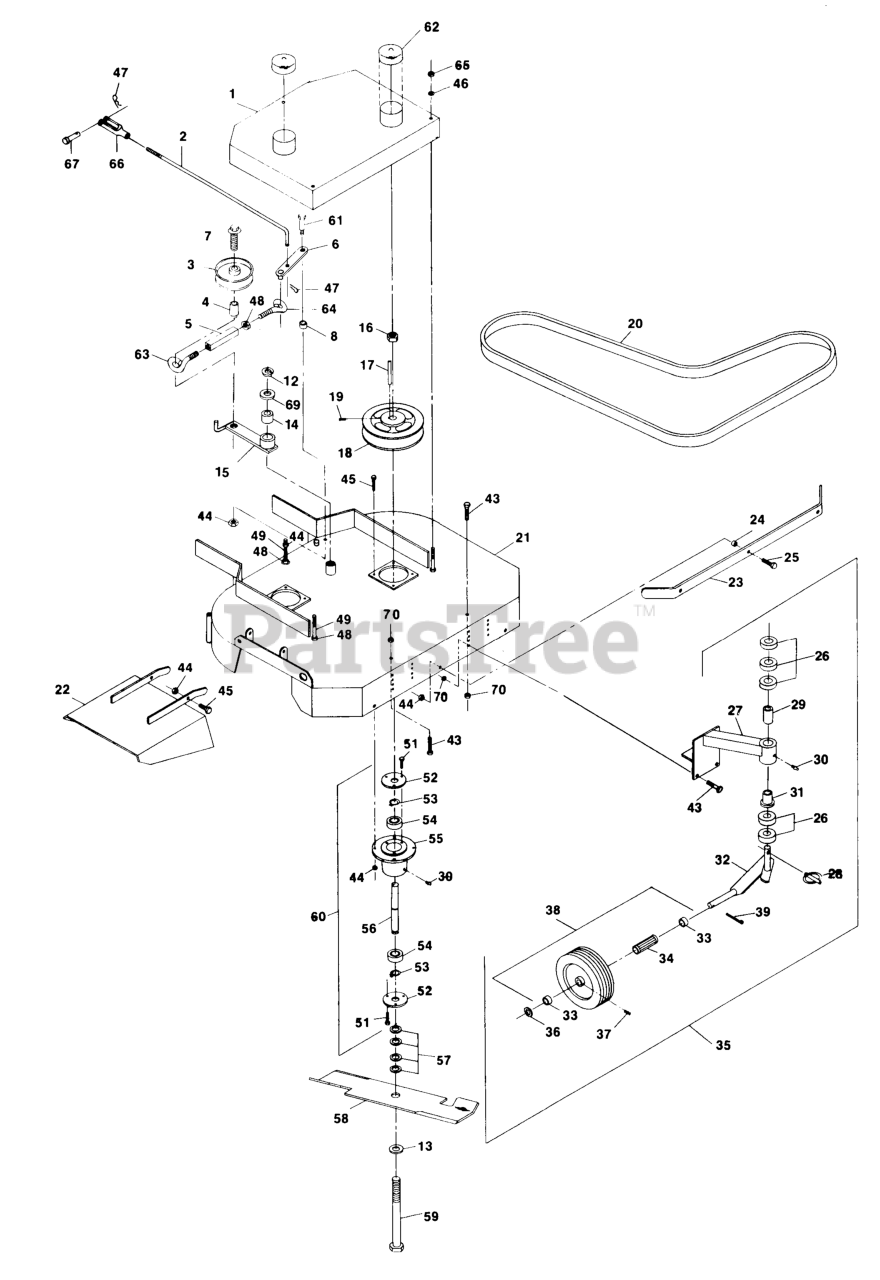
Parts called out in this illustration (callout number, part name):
5	BODY-TURNBUCKLE
14	BEARING,POWDERED METAL
18	PULLEY,CAST IRON
19	SCREW-SET
20	BELT,BLADE DRIVE
26	SPACER-CASTER
29	BEARING,STRAIGHT
32	WLD,STRUT CASTER
47	PIN-COTTER
49	BOLT,TAP HH
51	SCRWMACH PHS
55	HOUSING,CUTTER
56	SPINDLE,CUTTER
60	HOUSING,CUTTER COMPLETE
61	BOLT,SHLDR KSKH
62	CAP,SPINDLE GUARD
63	EYEBOLT-THREAD, LH
64	EYEBOLT-THREAD, RH
66	YOKE-ADJUSTABLE
67	PIN-CLEVIS
69	WASHER-SPINDLE
